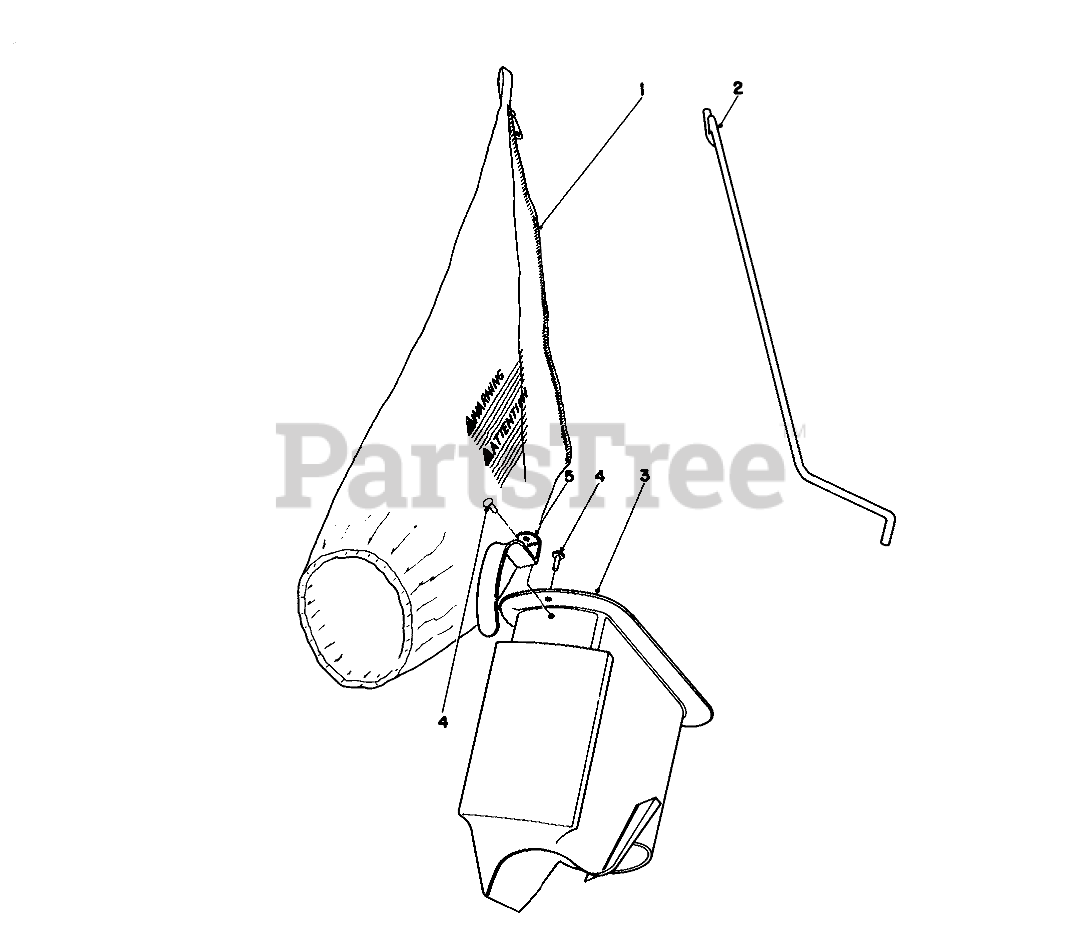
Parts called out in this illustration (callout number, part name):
1	BAG REPLACMNT44-0540
2	Bag Rod
3	Grass Chute (Incl. Ref. #4 & 5)
4	RIVET 3/16 X 7/16
5	HANDLE-GRASS CHUTE
